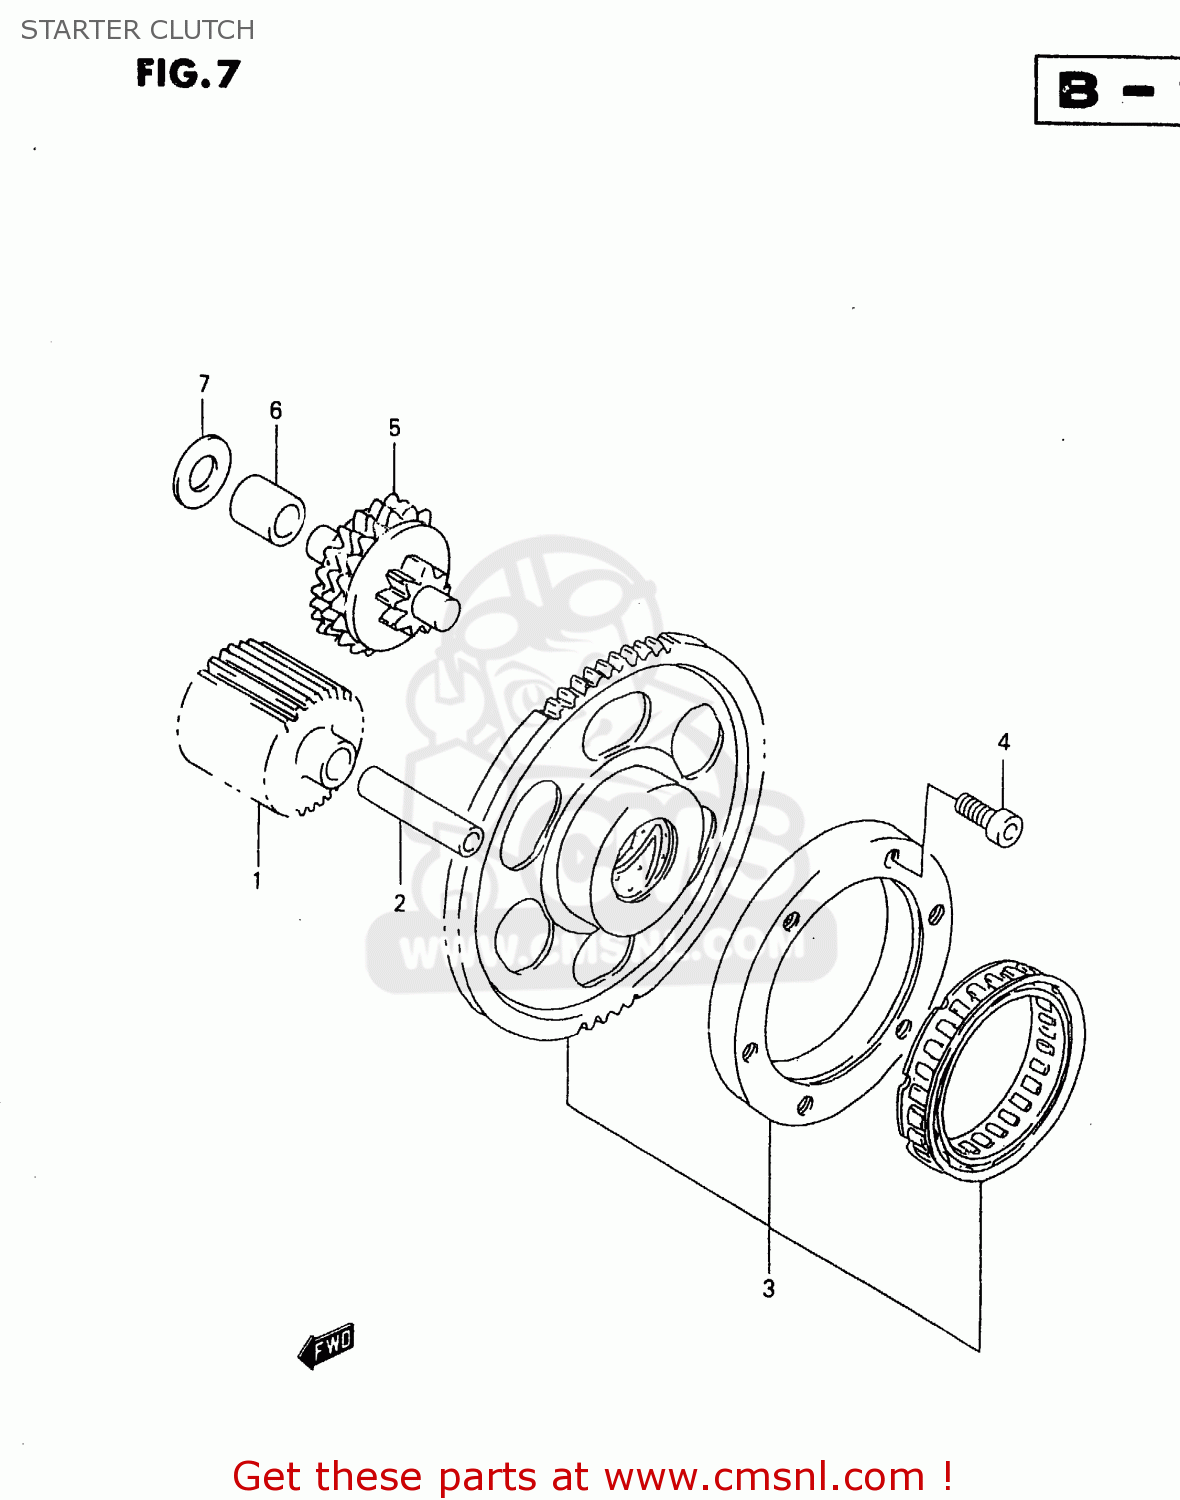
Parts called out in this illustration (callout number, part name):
1	GEAR,STARTER IDLE NO.1
2	PIN(7X11X55)
3	CLUTCH SET,STARTER
4	BOLT
5	LIMITER ASSEMBLY,STARTER IDLER GEAR
6	BUSH,LIMITER GEAR SHAFT
7	SHIM(10X20X1)
